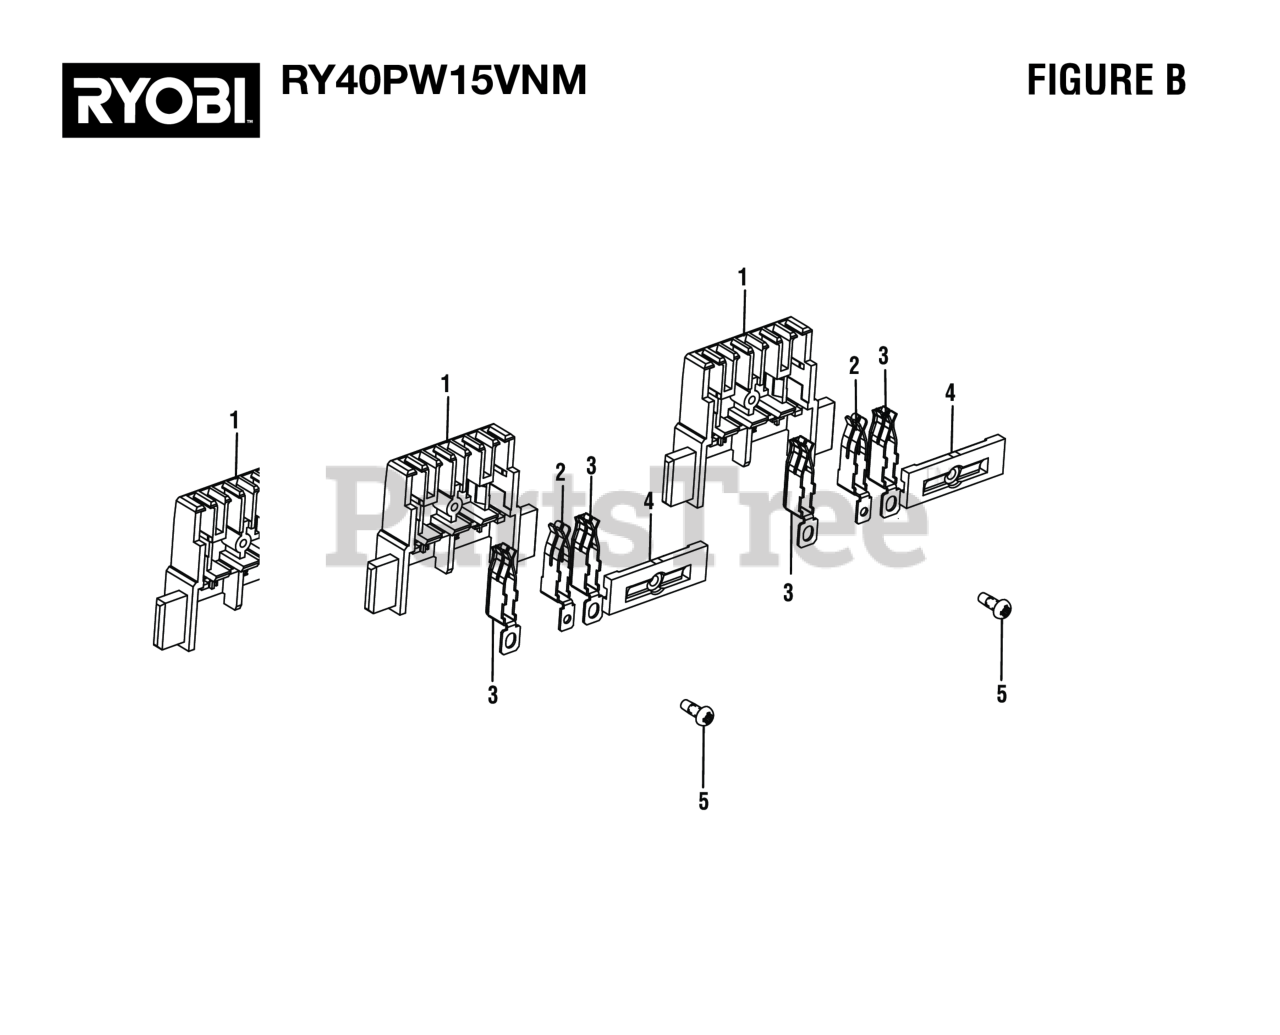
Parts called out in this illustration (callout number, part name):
1	Battery Contact Holder
2	STAMPING I BATTERY CONTACT PLATE TERMINA
3	Contact Plate Terminal
4	Battery Cover Connector
5	Screw (M3 x 8 mm, Pan Hd., Pan Hd)
